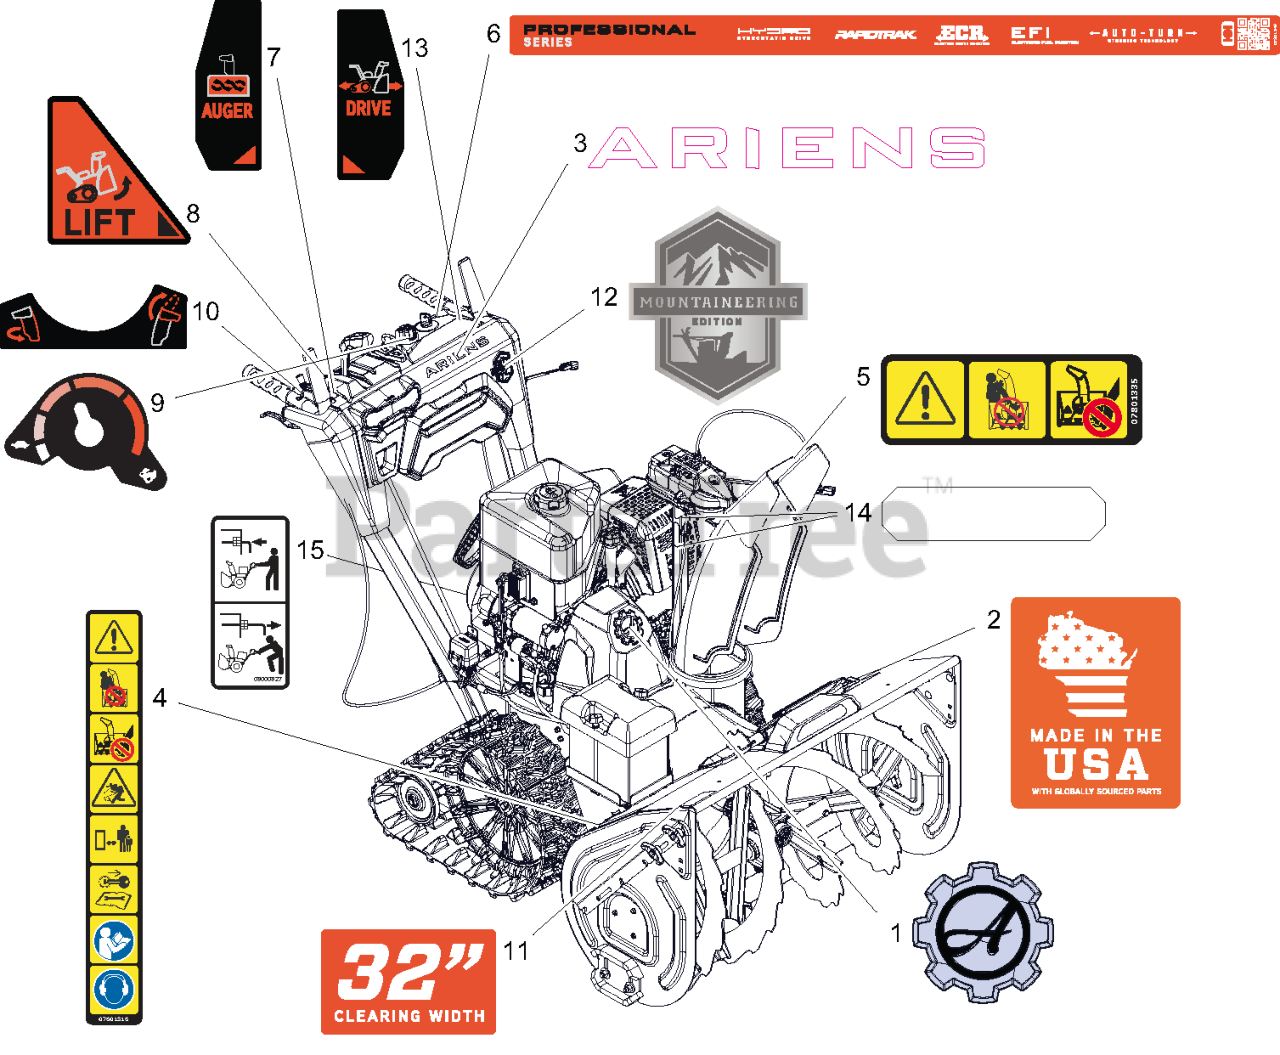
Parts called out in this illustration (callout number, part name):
1	DECAL, ARIENS - GEAR BADGE
2	DECAL- MADE IN USA
3	DECAL- ARIENS - 7.46"
4	DECAL- SAFETY - DANGER
5	DECAL- DANGER
6	DECAL- DASH - PRO TRK EFI
7	DECAL- CONTROL - AUGER
8	DECAL- CONTROL - TRACK LIFT
9	DECAL- CONTROL - EFI SPEED
10	DECAL- CONTORL - ECR
11	DECAL- CLEARING - 32
12	DECAL- BADGE - MOUNTAINEERING
13	DECAL- CONTROL - DRIVE TRACK
14	DECAL,REFLECTIVE,GEAR COVER
15	DECAL, BYPASS
